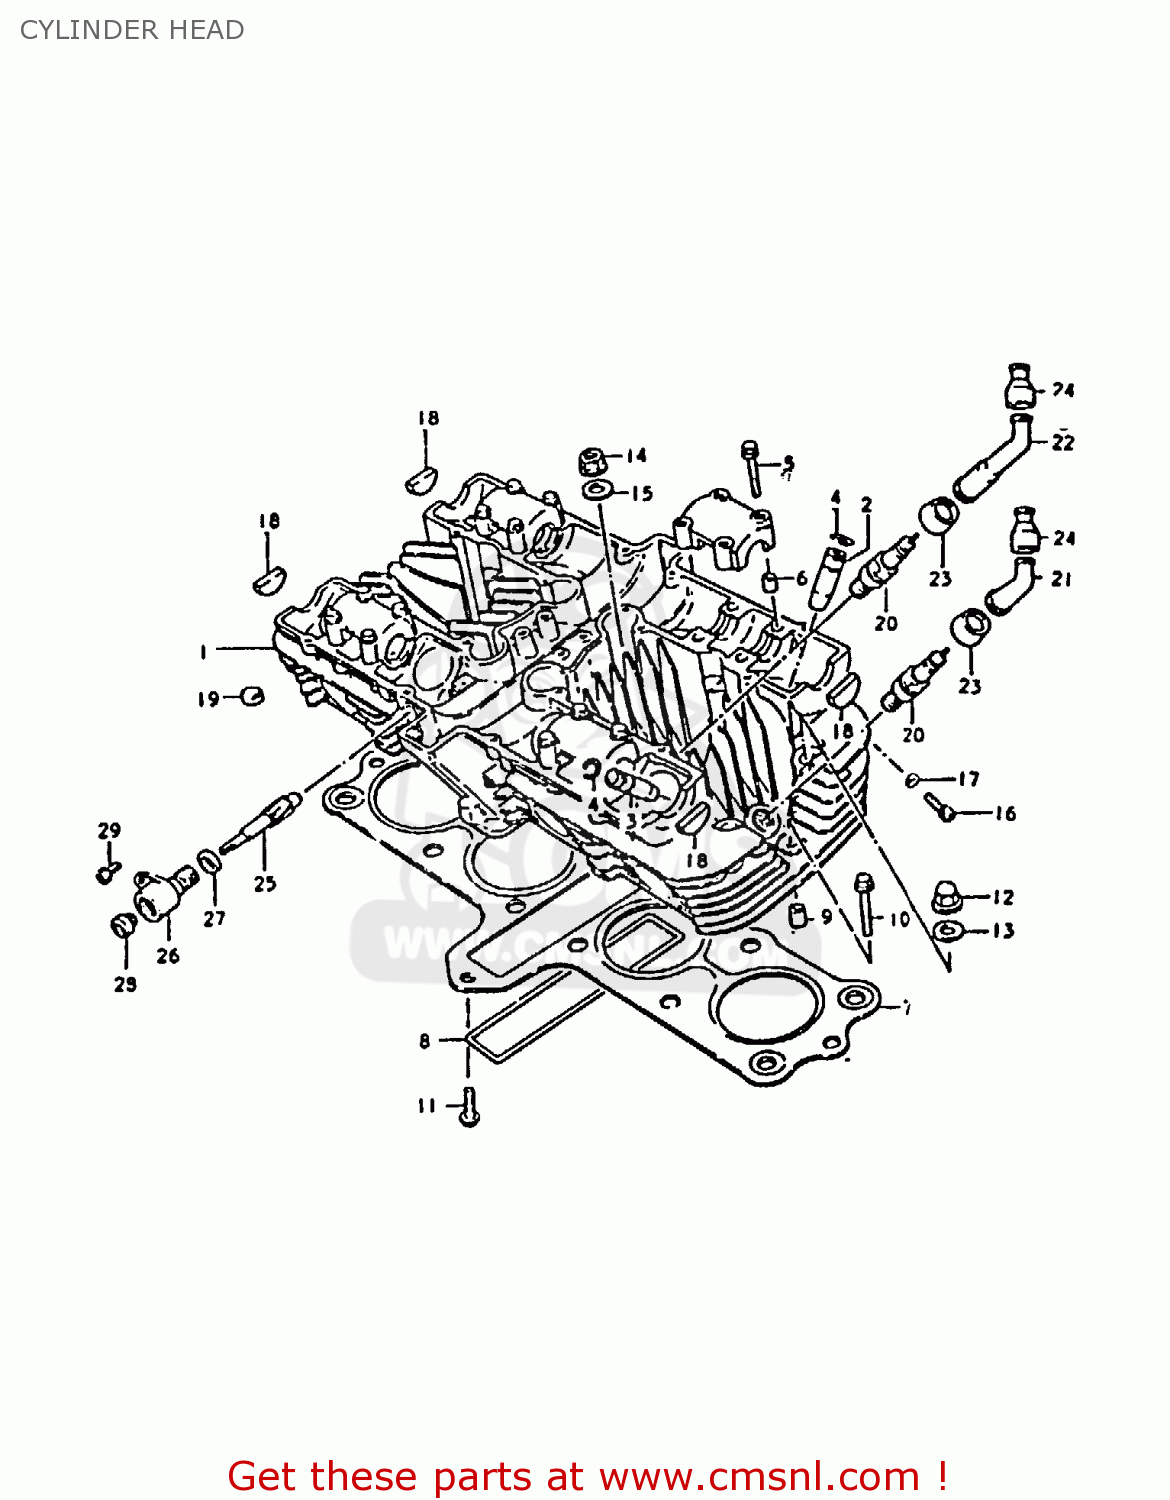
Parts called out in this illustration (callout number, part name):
1	HEAD ASSEMBLY,CYLINDER
2	GUIDE,VALVE
3	GUIDE,VALVE
4	RING,SNAP
5	BOLT(6X39)
6	PIN(6.2X8X11)
7	GASKET,CYLINDER HEAD (MCA)
8	O RING(D:3,ID:26X157)
9	PIN
10	BOLT,UNDER
11	BOLT
12	NUT
13	GASKET(10.5X22X2) (NAS)
14	NUT
15	WASHER(10.5X22X2.3)
16	BOLT
17	GASKET(5.3X9.3X1.2) (NAS)
18	PLUG
19	PAD
20	PLUG,SPARK
21	CAP,SPARK PLUG
22	CAP ASSY,SPARK PLUG
23	SEAL,SPARK PLUG
24	SEAL,SPARK PLU
25	GEAR,TACHOMETER DRIVEN
26	SLEEVE,TACHOMETER DRIVE GEAR
27	SEAL,TACHOMETER DRIVEN
28	SEAL,OIL(5X12X8)
29	SCREW(5X12)
